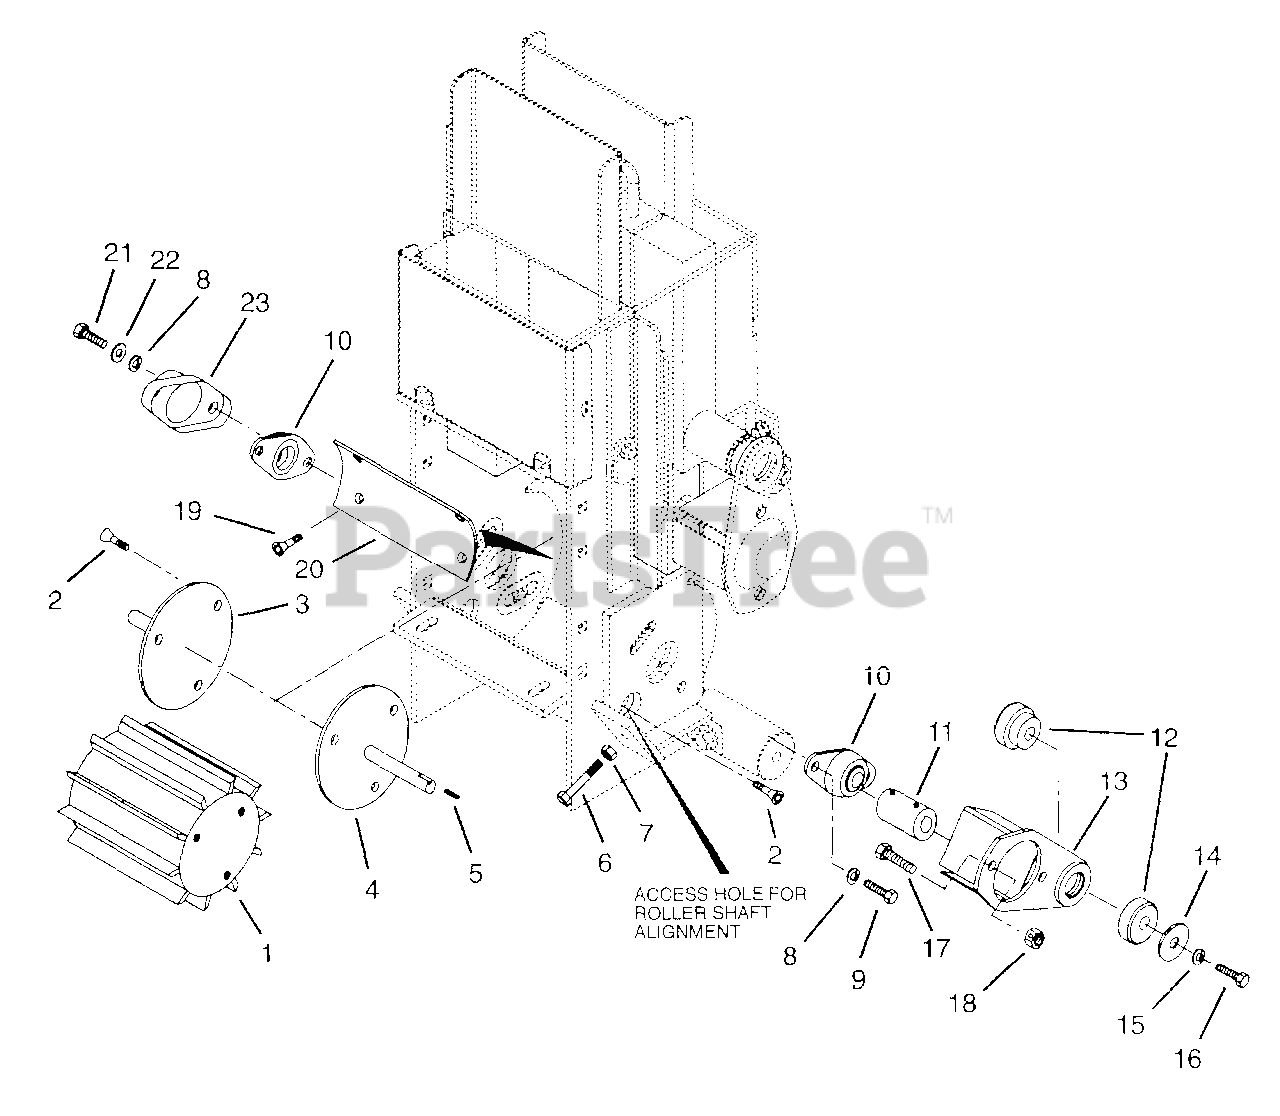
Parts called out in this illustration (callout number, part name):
2	Bolt-Flat Socket Head .50-13 x 1.0
3	Roller Shaft - Left
4	Roller Shaft - Right
5	Key-Square
6	Bolt-Hex-Full Thread .38-13 x 3.50
7	Nut-Hex .38-16
8	Washer-Locking .44 x .109
9	Bolt-Hex .44-14 x 1.25 Grade 5
10	Bearing Flange
12	Rubber Bushings
13	Torque Arm Weldment
14	Washer-Flat-Steel .50 x 2.25 x .13
15	Washer-Locking .50 x .125
16	Bolt-Hex .50-13 x 3.00 Grade 5
17	Bolt-Hex .50-13 x 1.50 Grade 5
18	Nut-Locking-Center .50-13
19	Screw-Machine .25-20 x .50 FLTCNTRSK
20	Wrapper-Inner
21	Bolt-Hex .44-14 x 1.50 Grade 5
22	Washer-Flat-Steel .505 x 1.00 x .062
23	Cover-Bearing Feed Roll
